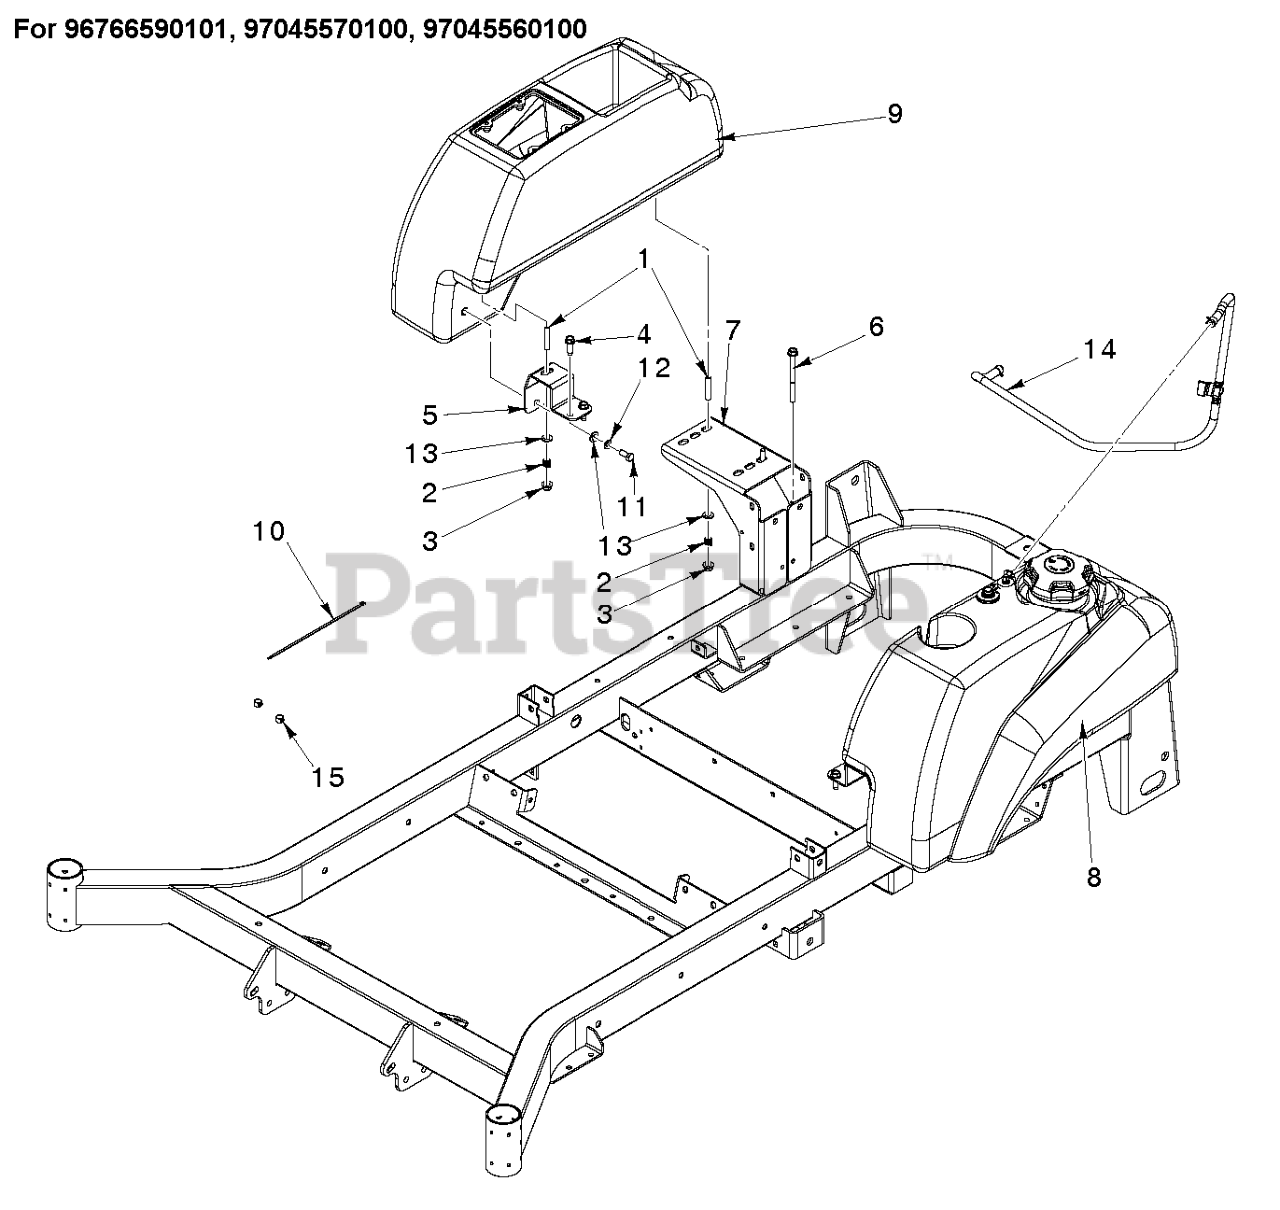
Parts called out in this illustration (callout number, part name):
1	STUD, 5/16C
3	NUT HEXAGON FLANGE 5/16-18 ST
4	SCREW HEX HEAD W/ WASHER 5/16-
5	SUPPORT.PNT.TANK.FRONT.STAMPED
6	BOLT.HEX.FLNG.5/16-18X3.75
7	MOUNT, TANK, ZT BLK
8	FUEL TANK ASSY LH MZ 2019
9	FENDER CONSOLE
10	TIE, PLASTIC
11	SCREW HEXAGON HEAD SCREW 5/16-
12	WASHER SPRING LOCK WASHER WITH
13	WASHER 11/32 X 11/16 X 14 GA T
15	TUBE.PURGE.FUEL.1875
